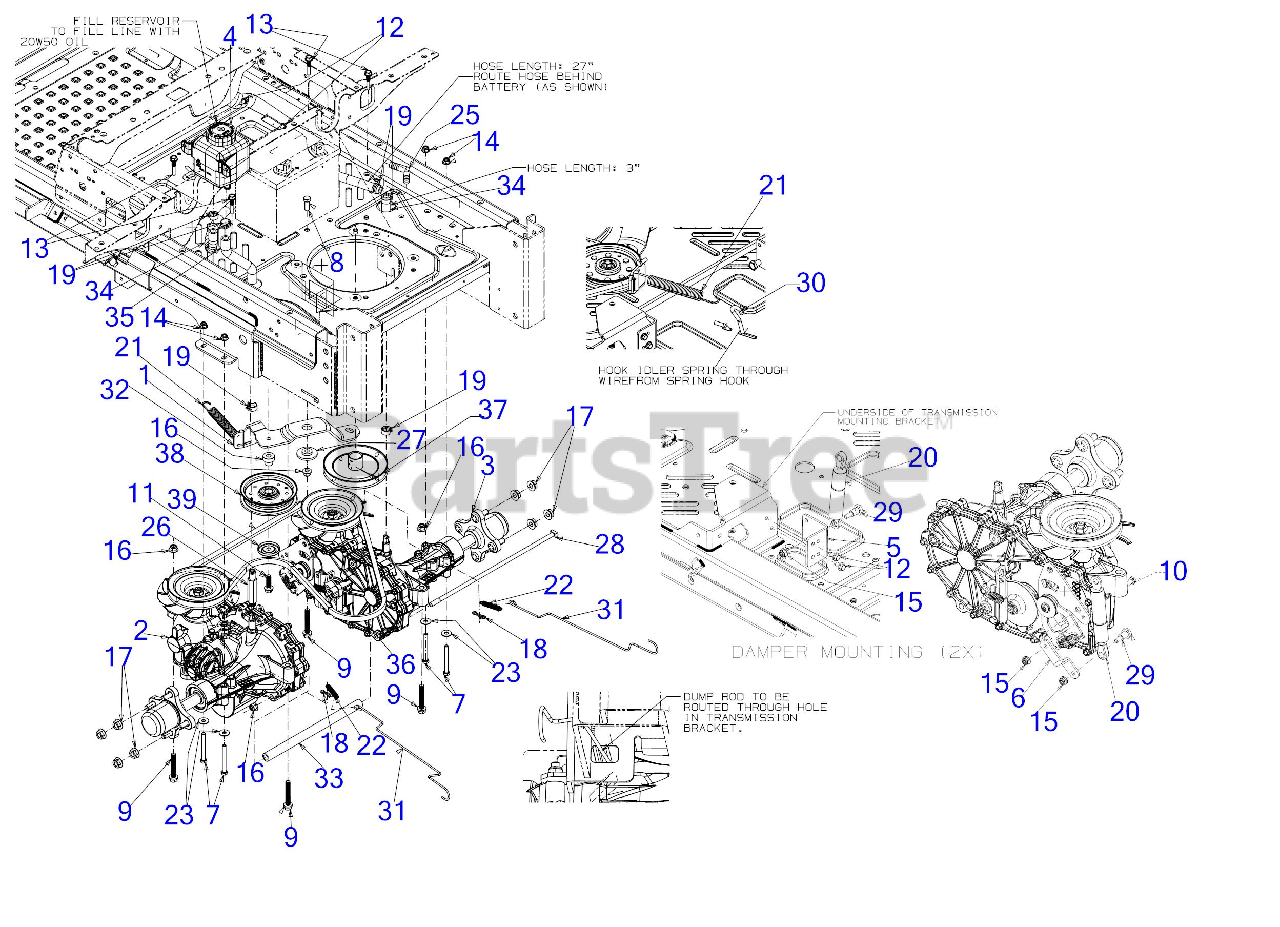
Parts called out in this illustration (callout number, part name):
1	IDLER BRACKET ASSEMBLY
2	HYDRO TRANSMISSION ASSEMBLY (LH)
3	HYDRO TRANSMISSION ASSEMBLY (RH)
4	HYDRAULIC TANK
7	HEX SCREW 5/16-18 x 2.75
8	SCREW 3/8-16 x 1 GR5
9	SCREW 3/8-16 x 2.25 GR5
10	SCREW 1/4-20 x .620 GR5
11	SCREW 3/8-16 X1.250
12	SCREW 1/4-20X.625
13	BELT KEEPER ROD .25 x 1.585
14	FLANGE LOCK NUT 5/16-18
15	FLANGE LOCK NUT
17	HEX FLANGE NUT 7/16-14
18	BOW TIE COTTER PIN 1/4-5/16
19	FUEL HOSE CLAMP
20	HYDRAULIC CYLINDER DAMPENER
21	EXTENTION SRING .75 DIA. x 6.85
22	EXTENSION SPRING .380 ODX 2.000 LG
23	FLAT WASHER
25	90 DEGREE NYLON FITTING
26	EXTENSION FITTING 9/16-18
27	SHOULDER SPACER
28	SUPPORT TUBE ROD
29	SHOULDER BOLT .395 DIA x .56 LG
30	IDLER SPRING HOOK
32	SHOULDER SPACER
33	TRANSMISSION SPACER .75OD x 11.31
34	FUEL LINE 1/2" ID
35	EXPANSION TANK HOSE
36	TRANSMISSION DRIVE BELT A x 67
37	TRANMISSION DRIVE PULLEY
38	IDLER PULLEY 4.25 DIA
39	IDLER PULLEY CAP
